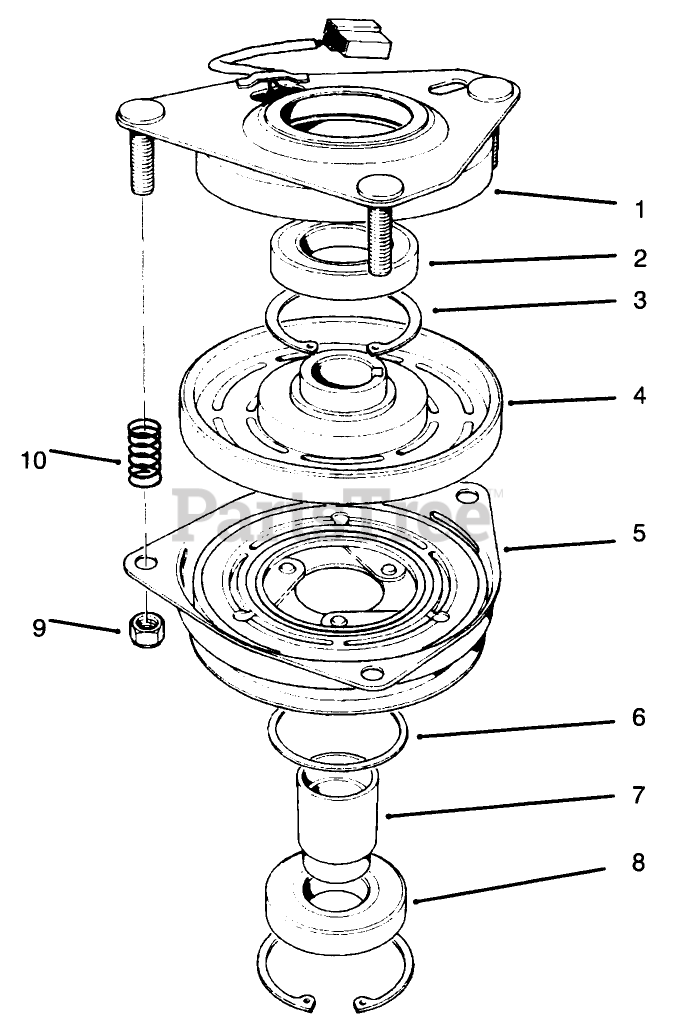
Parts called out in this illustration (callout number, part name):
1	Field Assembly (Incl. Ref. #2 & 3)
2	BEARING-FIELD
3	RING-RETAINING
4	Field Coil, Rotor & Bearing (Incl. Ref. #1)
5	Armature & Pulley Assembly (Incl. Ref. #3, 6, 7 & 8)
6	SPACER-BEARING, PULLEY
7	COLLAR-BEARING
8	BEARING-PULLEY
9	NUT-LOCK
10	SPRING
